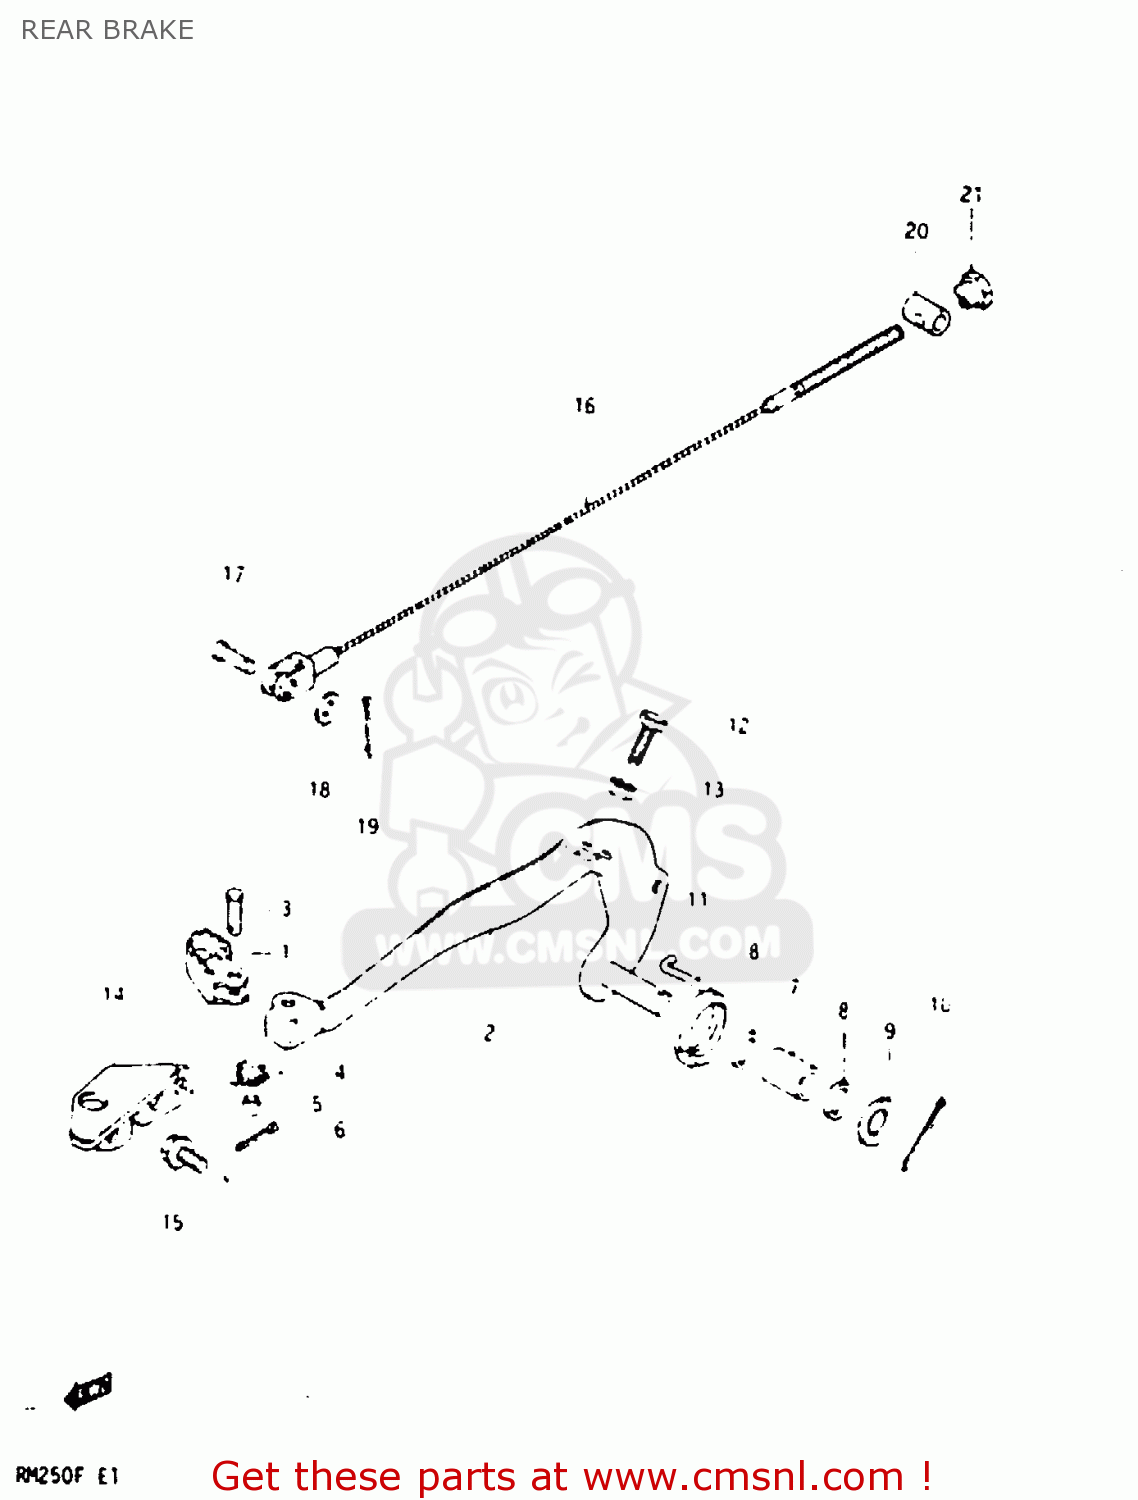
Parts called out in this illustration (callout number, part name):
1	PEDAL,BRAKE
2	ARM,BRAKE PEDAL
3	PIN
4	SPRING
5	SPACER(9.2X9X6.5)
6	PIN
7	BUSHING
8	O RING(D:2.4,ID:12.3)
9	WASHER
10	PIN 30X20
11	SPRING
12	BOLT
13	NUT
14	PROTECTOR,BRAKE PEDAL
15	BOLT
16	CABLE ASSEMBLY,REAR BRAKE
17	PIN(L:17.5)
18	WASHER
19	PIN 20X20
20	PIN
21	NUT (6MM)
